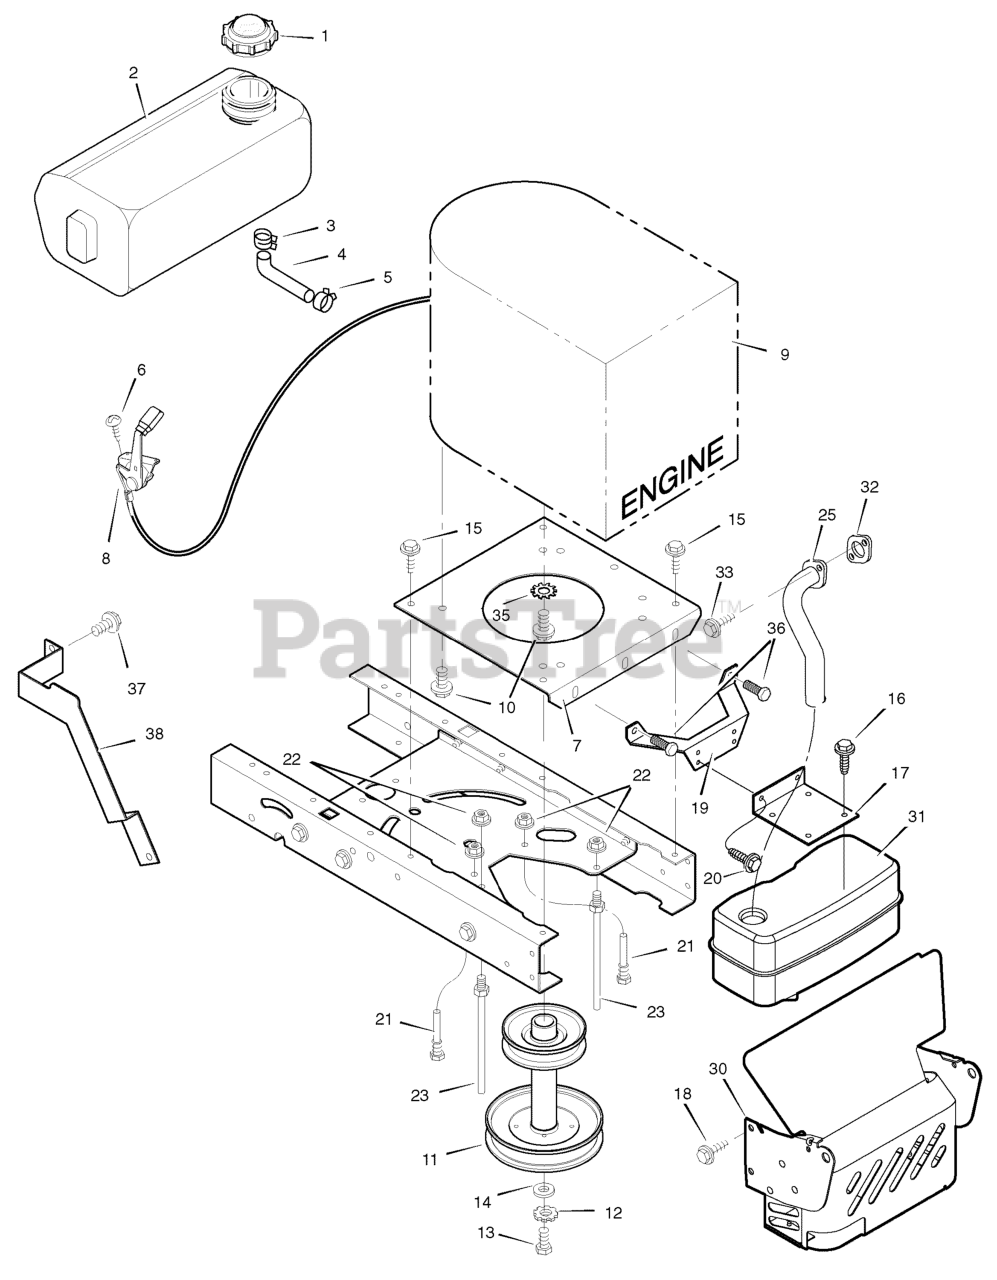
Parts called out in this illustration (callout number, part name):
1	Fuel Cap
2	Fuel Tank
3	Hose Clamp
4	Fuel Line (Must cut to length)
5	Hose Clamp
7	Plate, Engine
8	Throttle Control
9	Engine, Briggs & Stratton *
10	Bolt, Engine Mount
11	STACK PULLEY ASSEMBLY
12	Lockwasher
13	Bolt, Hex
17	Bracket, Muffler
19	Bracket, Muffler Mount
21	Guide, Belt
22	Nut, Flange
23	Guide, Belt
25	Exhaust Tube, Single
30	Shield, Heat
31	Muffler
32	GASKET, Exhaust
33	Screw, Adapter
35	Washer, 3/8 Star
37	Bolt, Washer Hex Head
38	Guard, Exhaust
